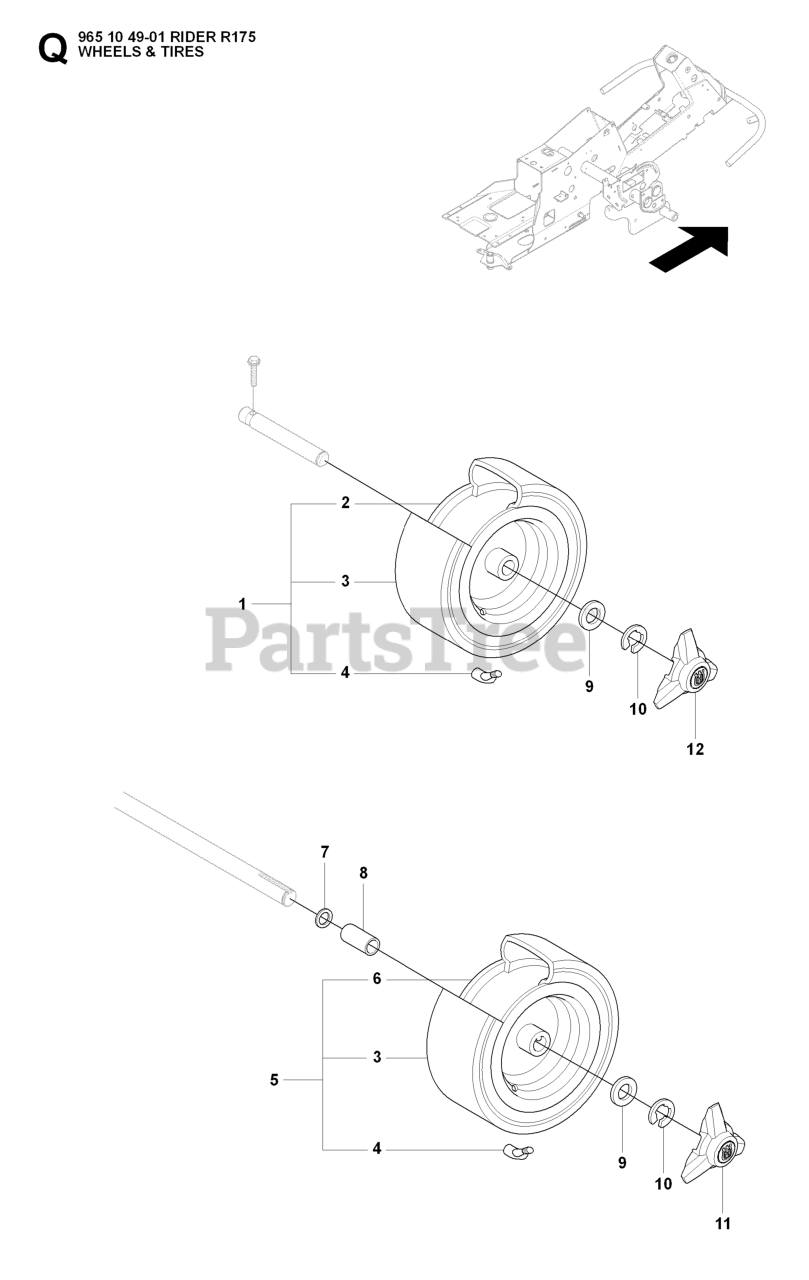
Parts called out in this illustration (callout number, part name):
5	WHEEL
6	RP RIM
10	SPACE SLEEVE
12	RETAINING RING
